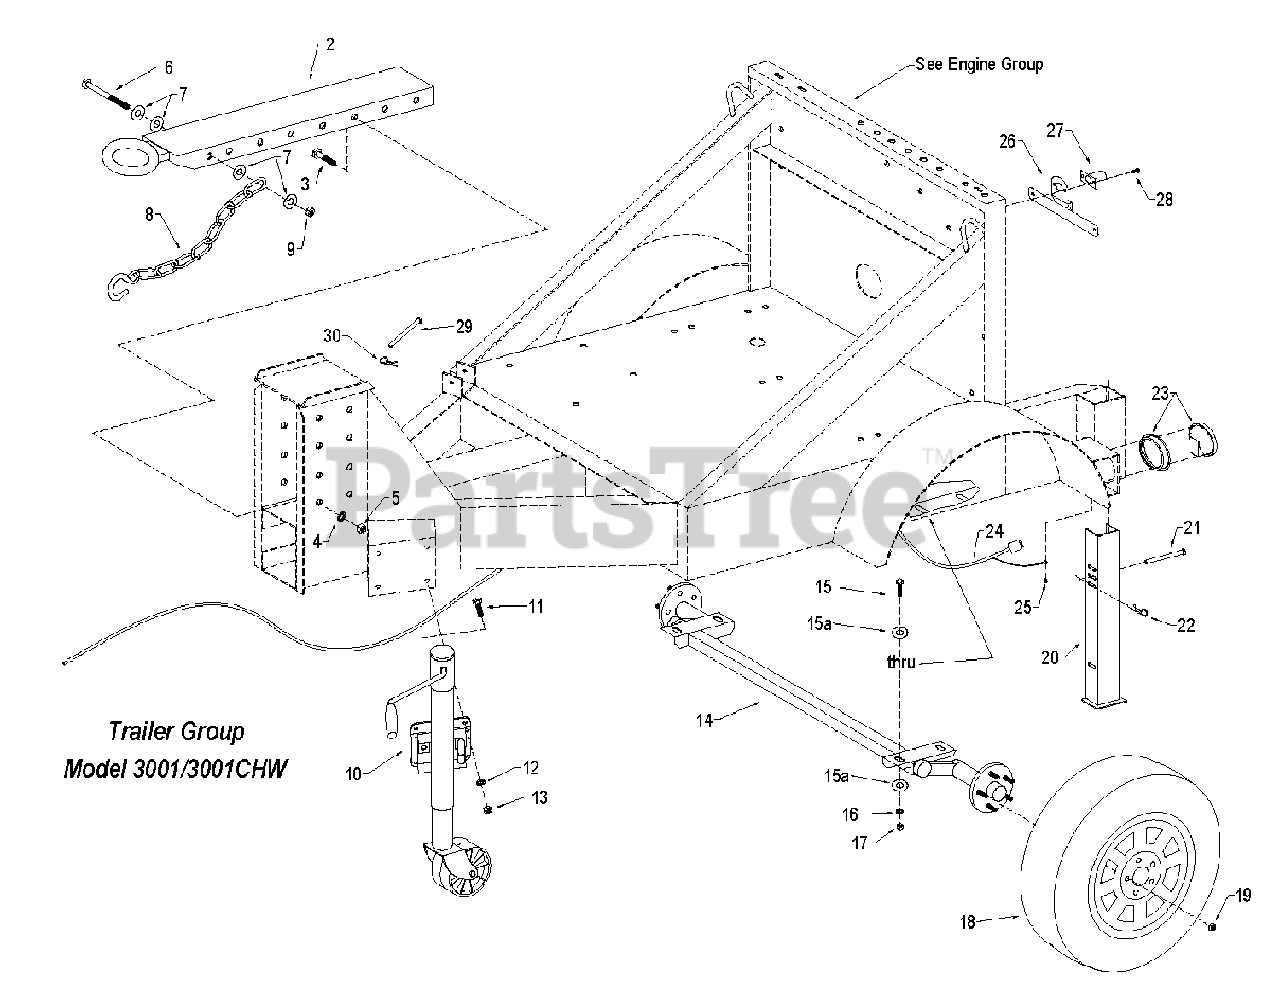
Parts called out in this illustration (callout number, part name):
1	Loader Base and Trailer Frame (See Engine Group)
3	1/2-13 x 1-1/4 Hex Bolt
4	1/2 Lock Washer
5	1/2-13 Reverse Lock Nut
6	1/2-13 x 7 Hex Bolt
7	1/2 Flat Washer
8	Safety Chain
9	1/2-13 Reverse Lock Nut
10	Dual Wheel Jack
11	3/8-16 x 1 Hex Bolt
12	3/8 Lock Washer
13	3/8-16 Lock Nut
14	Torflex Axle
15	1/2-13 x 1-1/4 Hex Bolt
16	1/2 Lock Washer
17	1/2-13 Hex End Lock Nut
18	Tire & Wheel Assembly
20	Support Leg
21	3/8 x 4-1/2 Clevis Pin
22	Bridge Pin
23	Stop & Tail Light Assembly
24	Wiring Harness
25	#10 x 1/2 Self-Taping Screw (Tail Light Ground)
26	License Bracket
27	License Light
28	1/4-20 x 1 Hex Bolt (Bolts License Light Assembly to Frame)
29	3/8 x 4-1/2 Clevis Pin
30	Bridge Pin
